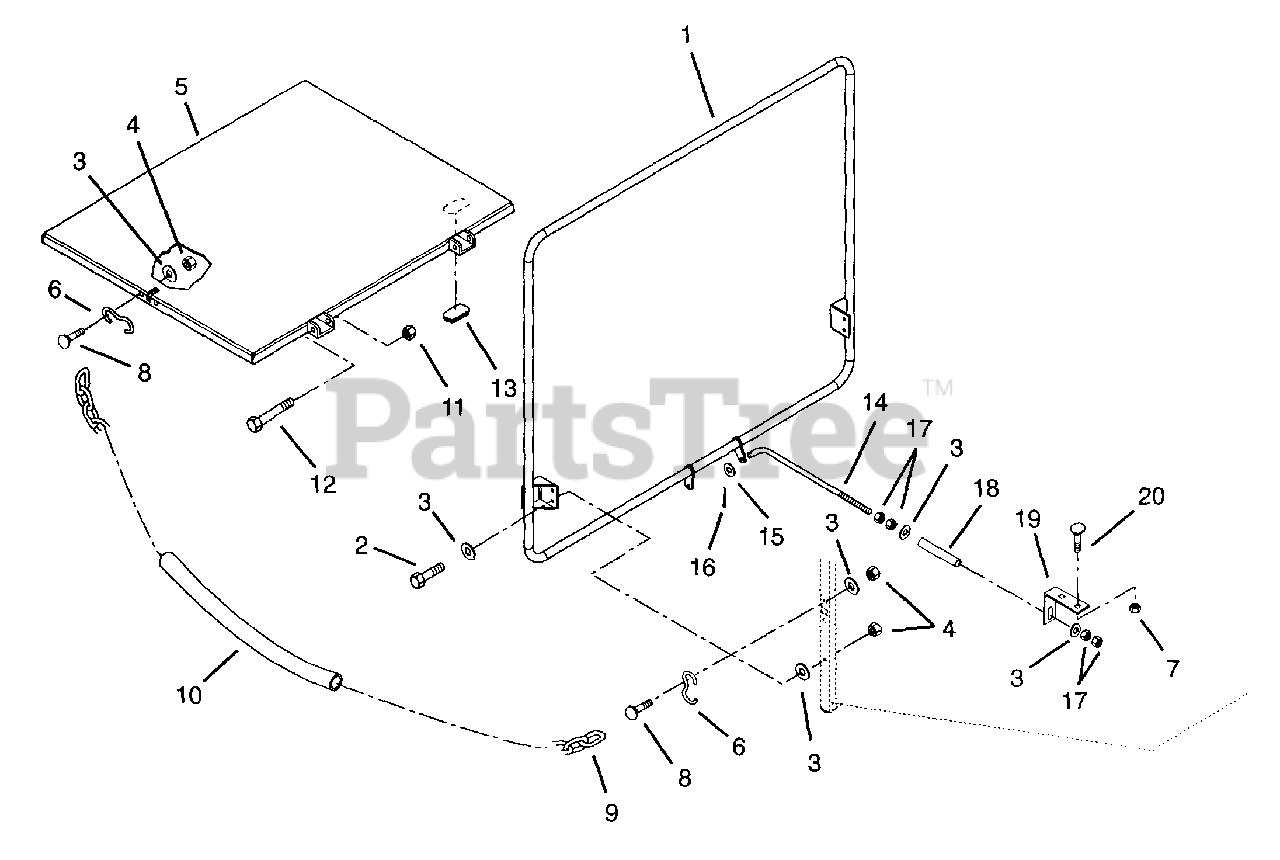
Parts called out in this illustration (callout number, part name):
1	Feed Control Bar
2	Bolt-Hex .38-16 x 1.00 Grade 5
3	Washer-Flat-Steel .438 x 1.0 x .O83
4	Nut-Locking-Center .38-16
5	Apron Weldment
6	Link-End
7	Nut-Locking-Center .38-16
8	Bolt-Round Head Square Neck .38-16 x 1.00
9	Apron Chain
10	Vinyl Tubing 1-1/2"
11	Nut-Locking-Center .50-13
12	Bolt-Hex .50-13 x 4.00 Grade 5
13	Reflex Reflector
14	Rod Valve Stop
15	Washer-Flat-Steel .344 x .688 x .065
16	Pin-Cotter .12 x .75
17	Nut-Hex .38-16
18	Tubing-Urethane .438 x .688
19	Bracket-Valve Stop
20	Bolt-Round Head Square Neck .38-18 x .75
